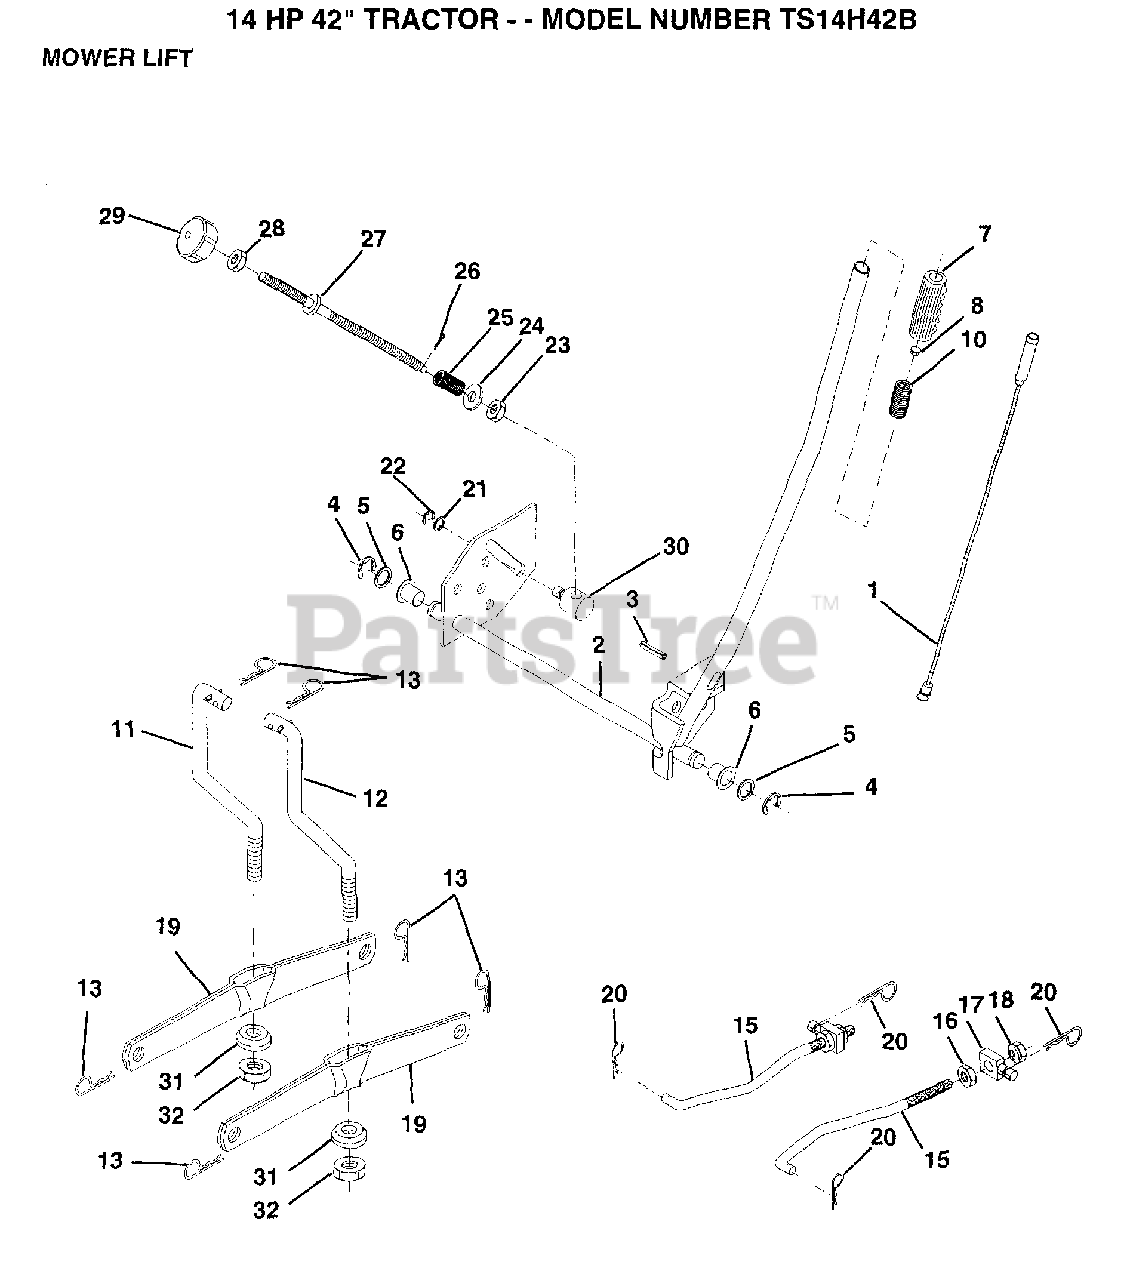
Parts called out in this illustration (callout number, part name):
1	WIRE.ASM.INNER
2	SHAFT.ASM.LIFT.RH
3	PIN GROOVE
5	WASHER
6	NYLON BEARING
7	GRIP HANDLE
15	LINK.FRONT
16	NUT
17	TRUNION
18	NUT.LK.W/WSH.1/2.
19	ARM SUSP REAR
20	RETAINER.SPRING
21	WASHER
22	KLIP RING
23	NUT T
24	WASHER
25	SPRING T
27	ROD LIFT LT
28	NUT
29	KNOB INF 3/8-16
30	TRUNION LT
31	BEARING PVT LH
32	NUT.LOCK.3/8-24
